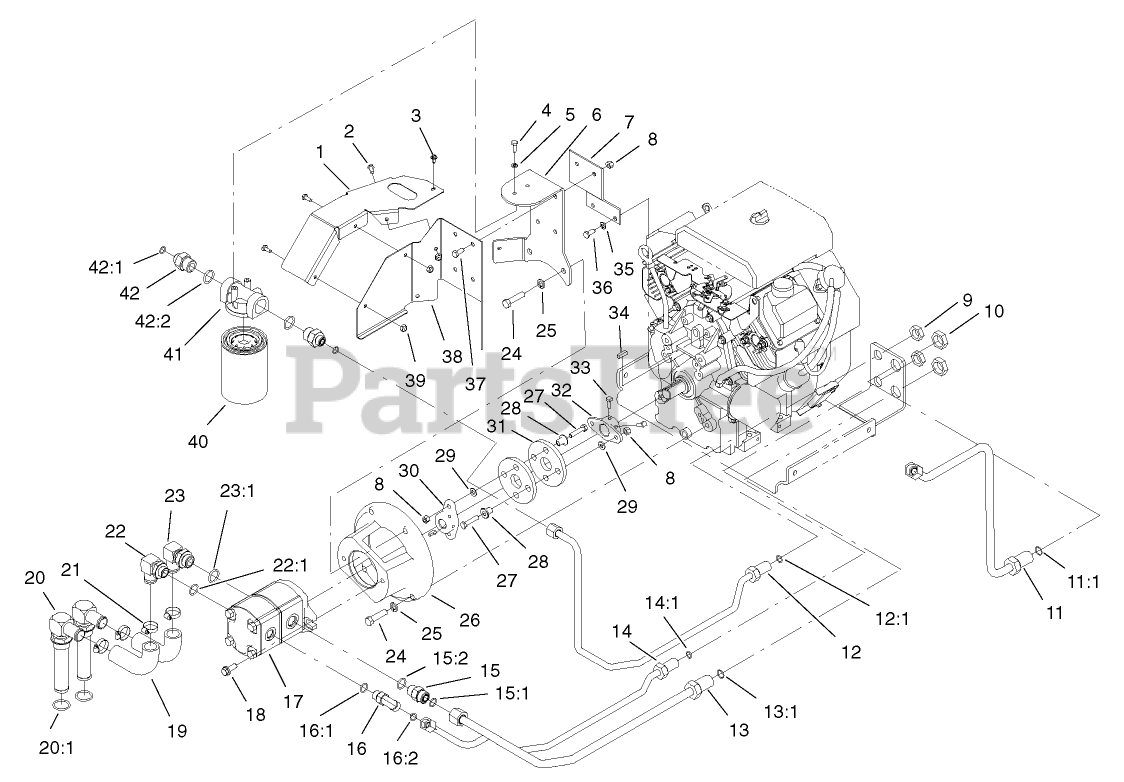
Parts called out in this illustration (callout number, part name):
1	SHIELD-HEAT
2	SCREW-HH
3	SCREW
4	SCREW-HH
5	WASHER-LOCK
6	BRACKET-SUPPORT, OIL FILTER
7	BRACKET-SUPPORT, OIL FILTER
8	NUT-LOCK, NI
9	NUT-BULKHEAD
10	NUT-LOCK, BULKHEAD
11	HYD TUBE ASM
11:1	O-RING
12	HYD TUBE ASM
12:1	O-RING
13	HYD TUBE ASM
13:1	O-RING
14	HYD TUBE ASM
14:1	O-RING
15	FITTING-STRAIGHT
15:1	O-RING
15:2	O-RING
16	FITTING-ELBOW-90 DEG
16:1	O-RING
16:2	O-RING
17	PUMP-GEAR, HYD
18	SCREW-HHF
19	HOSE-SUCTION, FORMED
20	STRAINER FITTING ASM
20:1	O-RING
21	CLAMP-HOSE
22	STEM-HOSE, 90 DEG
22:1	O-RING
23	FITTING-HYD, 90 DEG
23:1	O-RING
24	SCREW-HH
25	WASHER-LOCK
26	Mount-Pump
27	SCREW-HH
28	SPACER
29	WASHER-PLAIN
30	HUB-PUMP
31	COUPLING-RUBBER
32	HUB-ENGINE
33	SCREW-SQH
34	KEY-SQUARE
35	WASHER-LOCK
36	SCREW-HH
37	SCREW-HH
38	SHIELD-HEAT, FILTER
39	NUT-LOCK, NI
40	FILTER-OIL
41	HEAD-FILTER
42	FITTING-STR
42:1	O-RING
42:2	O-RING
